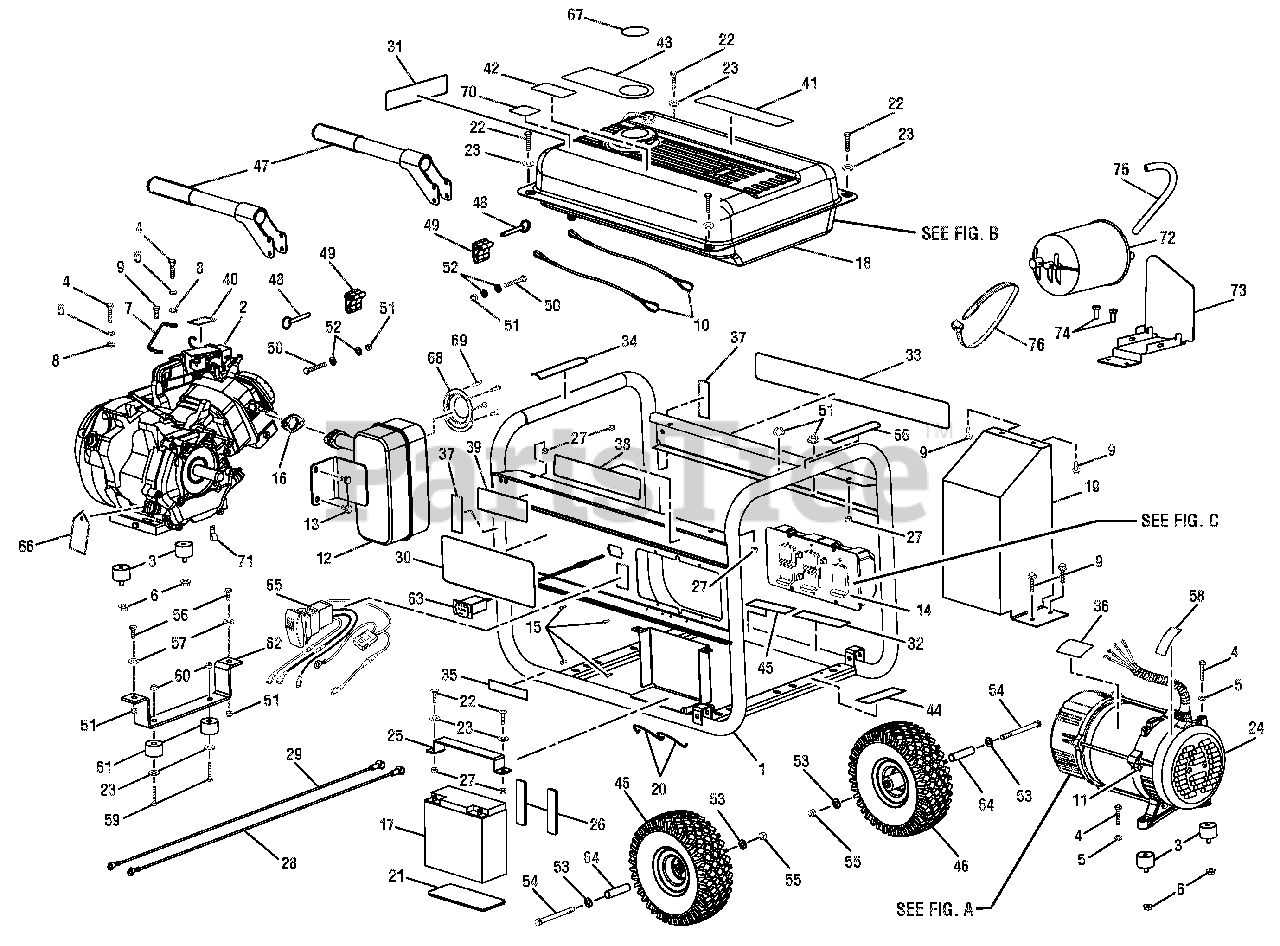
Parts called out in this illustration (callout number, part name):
1	CARRIER ASSEMBLY
2	Engine (Honda GX390)(Parts available at your local Honda dealer)
3	ISOLATOR
4	BOLT (5/16-18 X 1-1/2 IN HXHD)
5	LOCK WASHER (5/16 IN.)
6	FLANGE NUT (5/16-18 HEX HD.)
7	GROUND WIRE ASSEMBLY
8	STAR WASHER (5/16 IN.)
9	BOLT (5/16-18 X 3/4 IN HEX HD)
10	LANYARD (3/16 IN.)
11	GROUND LUG
12	MUFFLER
13	BOLT (5/16-24 X 5/8 IN.)
14	CONTROL PANEL ASSEMBLY
15	SCREW (6-20 X 3/8 IN.)
16	MUFFLER GASKET
17	BATTERY
18	FUEL TANK ASSEMBLY
19	HEAT SHIELD
20	CORD RETAINER
21	BATTERY BOX GASKET
22	BOLT (1/4-20 X 1 IN. HEX HD.)
23	WASHER (1/4 IN.)
24	GENERATOR HEAD W/AVR
25	BATTERY HOLD DOWN BRACKET ASSM
26	GASKET (BATTERY HOLD DOWN
27	LOCK NUT (1/4-20)
28	BATTERY CABLE (RED)
29	BATTERY CABLE (BLACK)
30	LOGO LABEL
31	STARTING INSTRUCTIONS LABEL
32	HOT SURFACE LABEL
33	DANGER DECAL
34	FIRE DANGER LABEL
35	ENGINE LUBRICANT LABEL
36	DATA LABEL
37	LOCKING PIN LABEL
38	HONDA LABEL
39	ELECTRIC START LABEL
40	CHOKE LABEL
41	QUICK START LABEL
42	CPSC LABEL
43	HANGTAG (ENGINE WARNING)
44	GROUND WARNING LABEL
45	COMBUSTION WARNING LABEL
46	WHEEL ASSEMBLY
47	HANDLE ASSEMBLY
48	RELEASE PIN (5/16 X 2 IN.)
49	HANDLE BRACKET SPACER
50	BOLT (5/16-18 X 2-1/4 IN HXHD)
51	LOCK NUT (5/16)
52	WASHER (5/16 IN.)
53	WASHER (3/16 IN.)
54	BOLT (3/8-16 X 4-1/4 IN HX HD)
55	NUT (3/8-16)
56	BOLT (5/16-18 X 1 IN. HEX HD.)
57	FLAT WASHER (5/16 IN.)
58	GROUND LABEL
59	BOLT (1/4-20 X 1-1/2 IN HX HD)
60	LOCK NUT (1/4-20)
61	RUBBER FOOT
62	FRONT FOOT
63	HOUR METER (120 VOLT)
64	WHEEL SPACER
65	ENGINE SWITCH
66	FIRE DISTANCE LABEL
67	FUEL STABILIZER LABEL
68	SPARK ARRESTOR
69	SCREW (8-32 X 3/8 IN.)
70	E85 LABEL
71	J-CLAMP
72	CANISTER
73	BRACKET
74	BOLT (5/16-18 X 3/4 IN.)
75	PURGE HOSE
76	CABLE TIE
